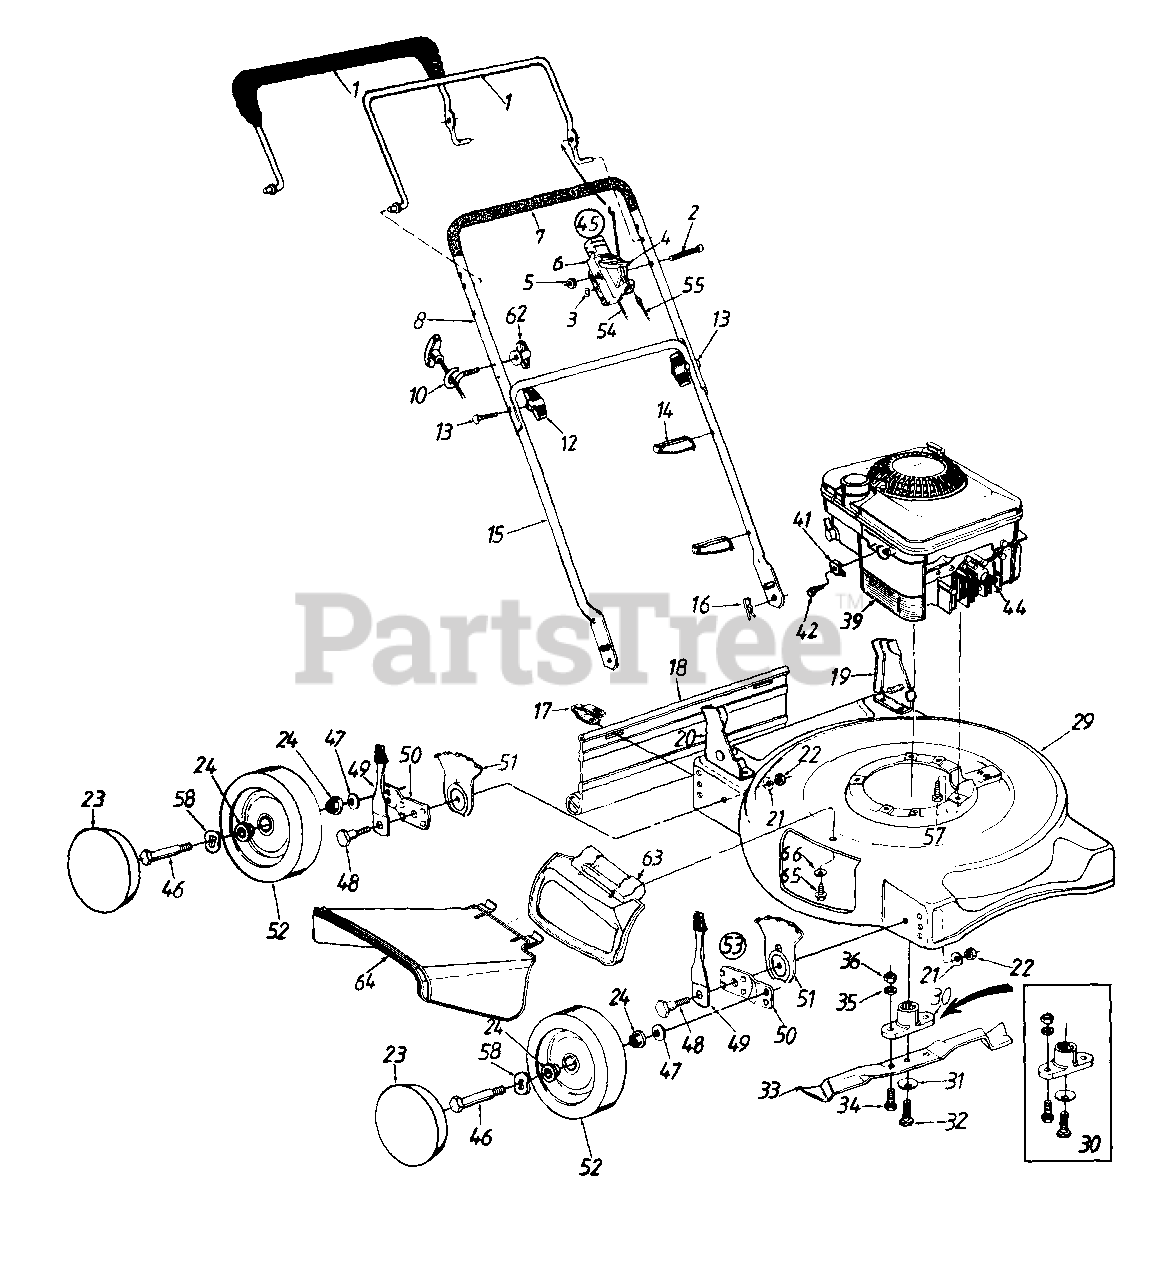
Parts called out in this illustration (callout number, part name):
1	Control Handle Ass'y.
2	Oval C-Sunk Scr.
3	Spr. Wash .66" I.D.
4	Throttle Lever
5	Hex L-Nut 1/4-20 Thd.
6	Throttle Body
7	Grip
12	Hand Knob
13	Curved Hd. Bolt 5/16-18 x 2" Lg.
14	Cable Tie
16	Hairpin Cotter
17	Hinge Clip
18	Rear Flap
22	Hex Nut 3/8-16 Thd.
23	Hub Cap
24	Bearing
29	20" Deck Ass'y.
30	Blade Adapter Kit
31	Bell-Wash .39" I.D.
32	Hex Bolt 3/8-24 x 1.5" Lg.
33	20" Mulching Blade
34	Hex Bolt 3/8-24 x 1" Lg.
35	L-Wash. 3/8" I.D.
36	Hex Nut 3/8-24 Thd.
39	Engine
41	Cable Clamp
42	Hex Self-Tap Scr. #10-32 x .62"
44	Spark Plug Boot
45	Throttle Box Comp.
46	Axle Bolt
47	Bell-Wash .400" I.D. x .88"
48	Shld. Bolt .50" Dia. x .357"
49	Spring Lever Ass'y. w/Knob
51	Height Adj .Plate
52	Wheel Ass'y. Comp.
53	Height Adj. Ass'y. Comp.- R.F. & L.R.
54	Throttle Cable - 51"
55	Control Cable - 39"
57	Hex L-Wash. Hd. Scr. 3/8-16 x 1.0" Lg.
58	Wave Washer.51" I.D.
62	Handle Knob 1/4-20 Thd.
63	Mulching Plug
64	Chute Deflector
65	Bell-Wash. 1/4" I.D.
66	Hex Wash. Hd. TT-Tap Scr. 1/4-20 x .5" Lg.
